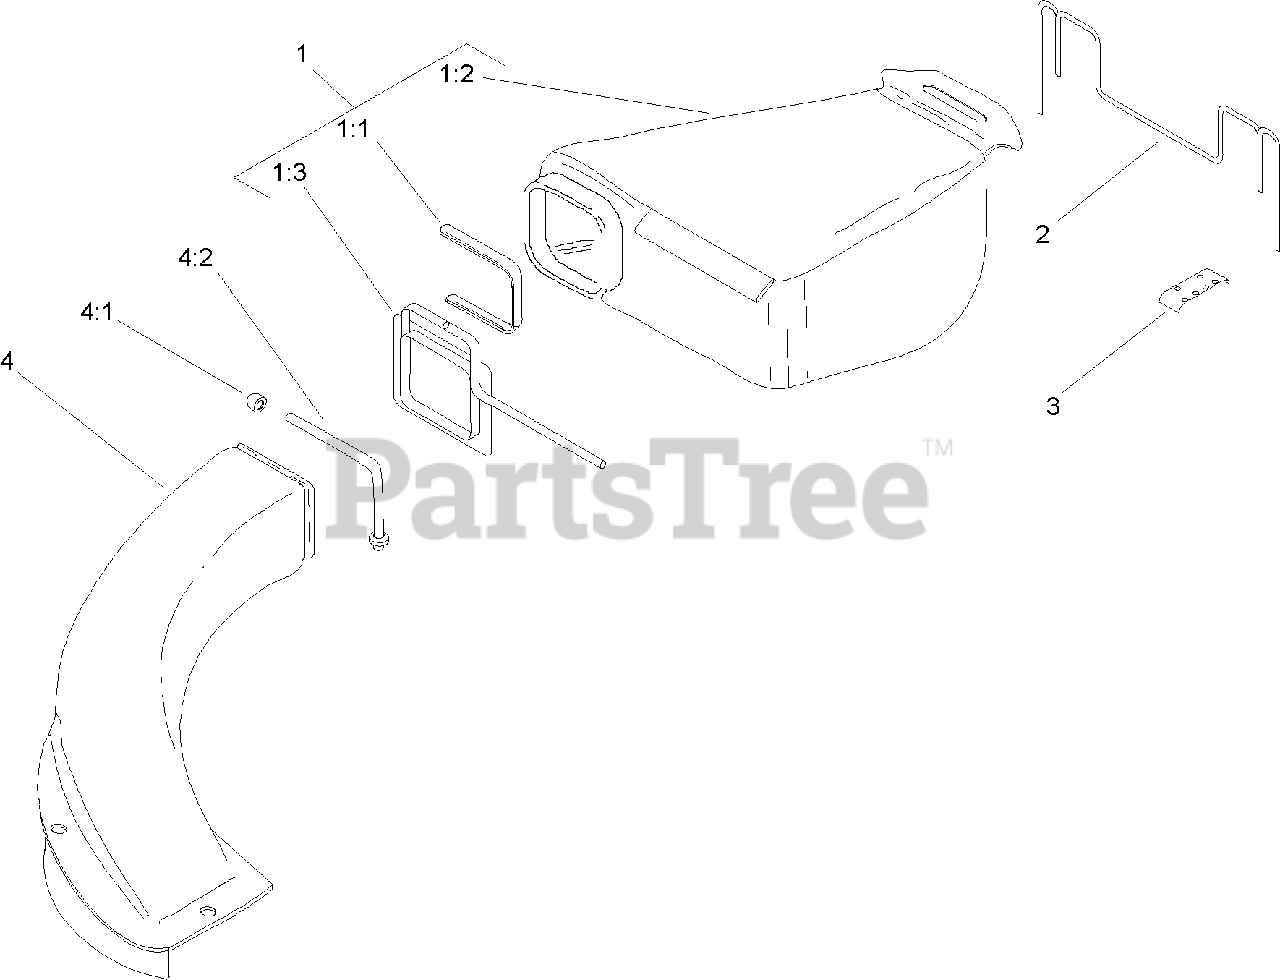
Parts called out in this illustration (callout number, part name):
1:1	STRAP-TIE
1:2	REPLACEMENT BAG ASM
2	HANGER-WIRE
3	CLAMP-HANGER
4	CHUTE AND SUPPORT ASM
4:1	NUT-CAP
4:2	SUPPORT-CHUTE
